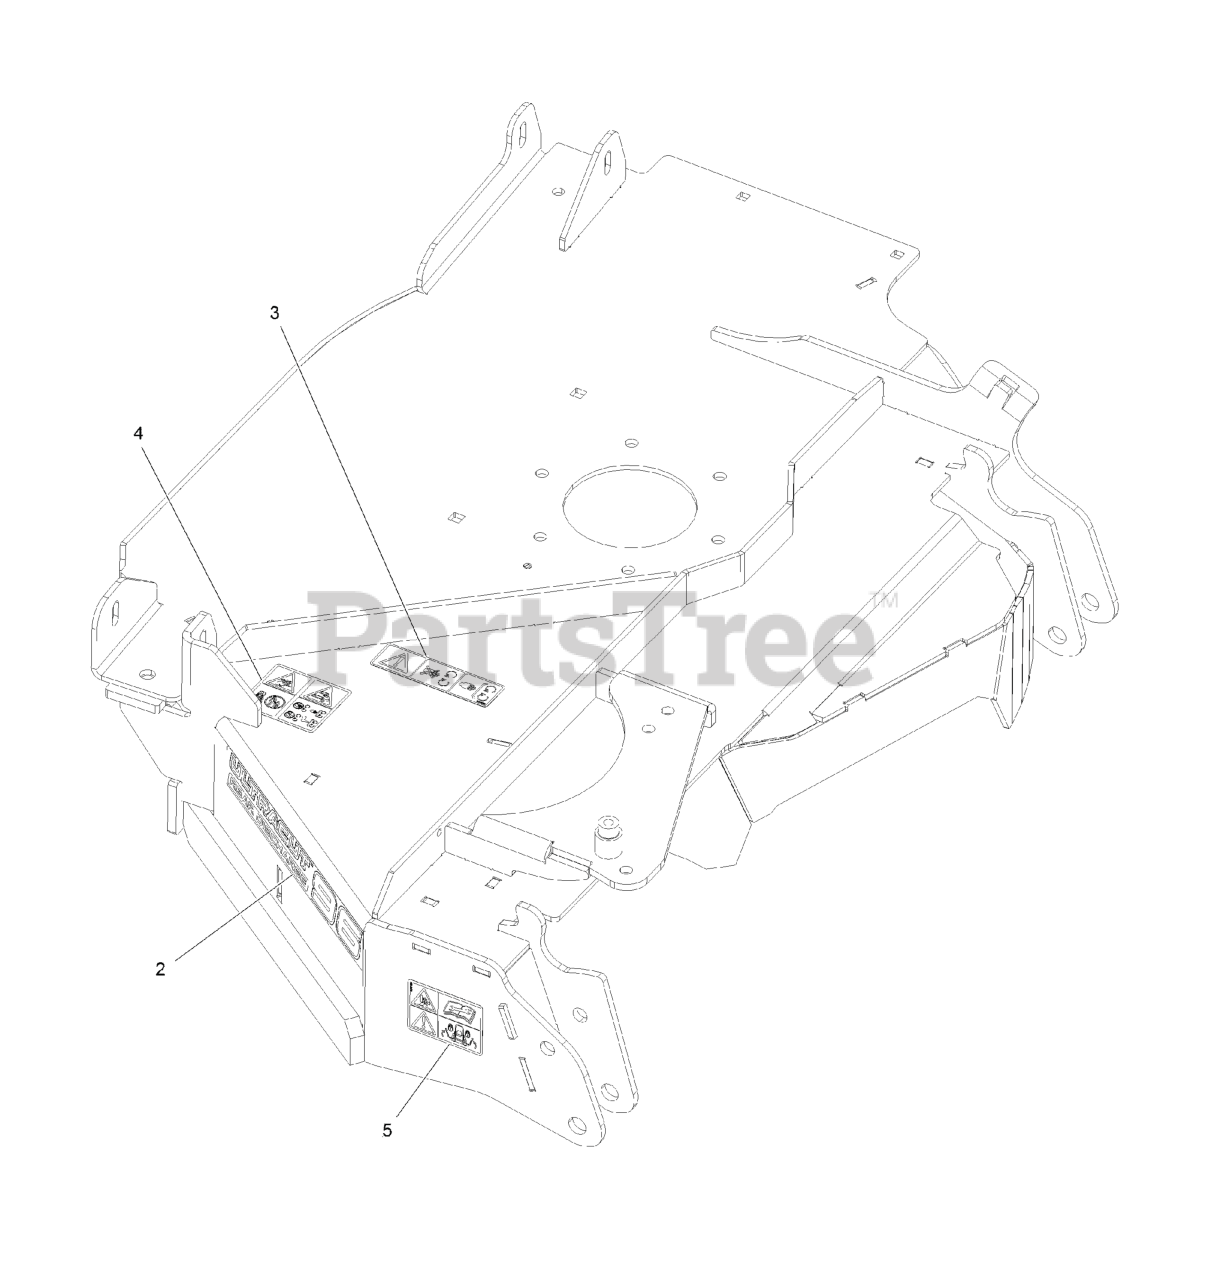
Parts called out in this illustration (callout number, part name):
2	DECAL-ULTRACUT 96-RD
3	DECAL-COVER, MISSING
4	DECAL-DANGER, THROWN OBJECT
5	DECAL-WARNING, PINCH POIN
